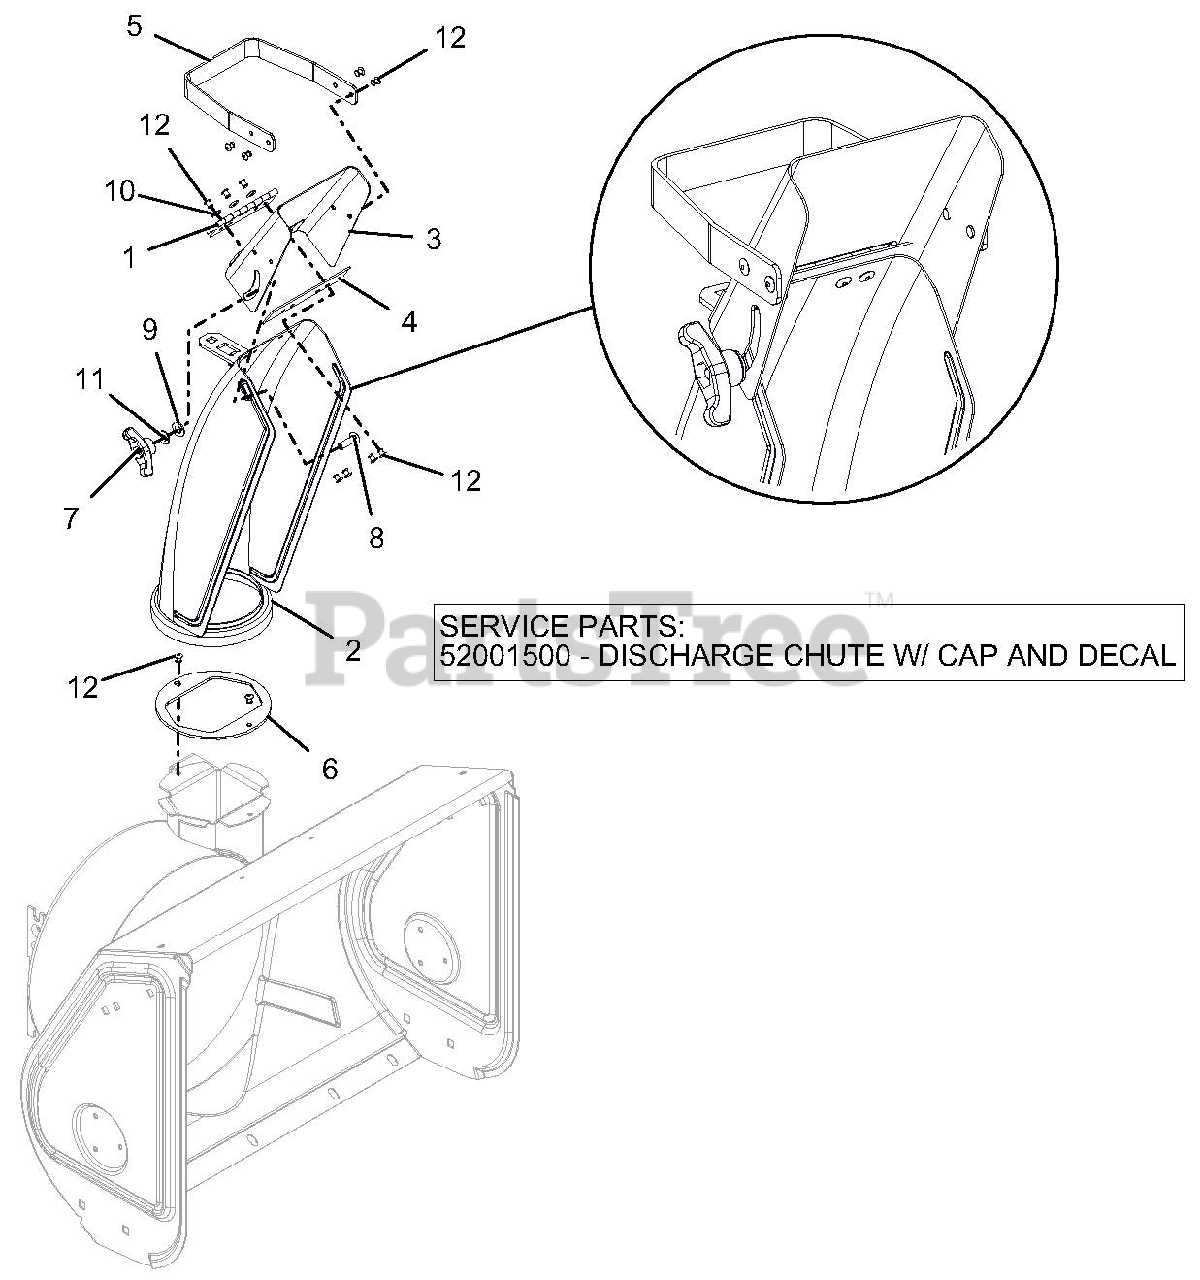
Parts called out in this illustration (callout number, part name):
2	CHUTE, COMPACT - TALL
3	CAP, SMALL DEFLECTOR-MANUAL
4	CAP SEAL 5.25
5	HANDLE, DEFLECTOR
6	BAFFLE, COMPACT DISCHARGE
7	KNOB,WING .31-18 UNC NYL/TALC
8	@BLT-RHDSSQNK .31-18X1.00 G5YZ
9	WSHR-FL-NY .375X.75X.060
10	WSHR-FL-STL .196X.500X.06 YZ
11	@WSHR-FL-STL.344X.688X.065YWZC
12	RVT-POP .187 YZ
13	CHUTE, DISCHARGE W/CAP & DECAL
